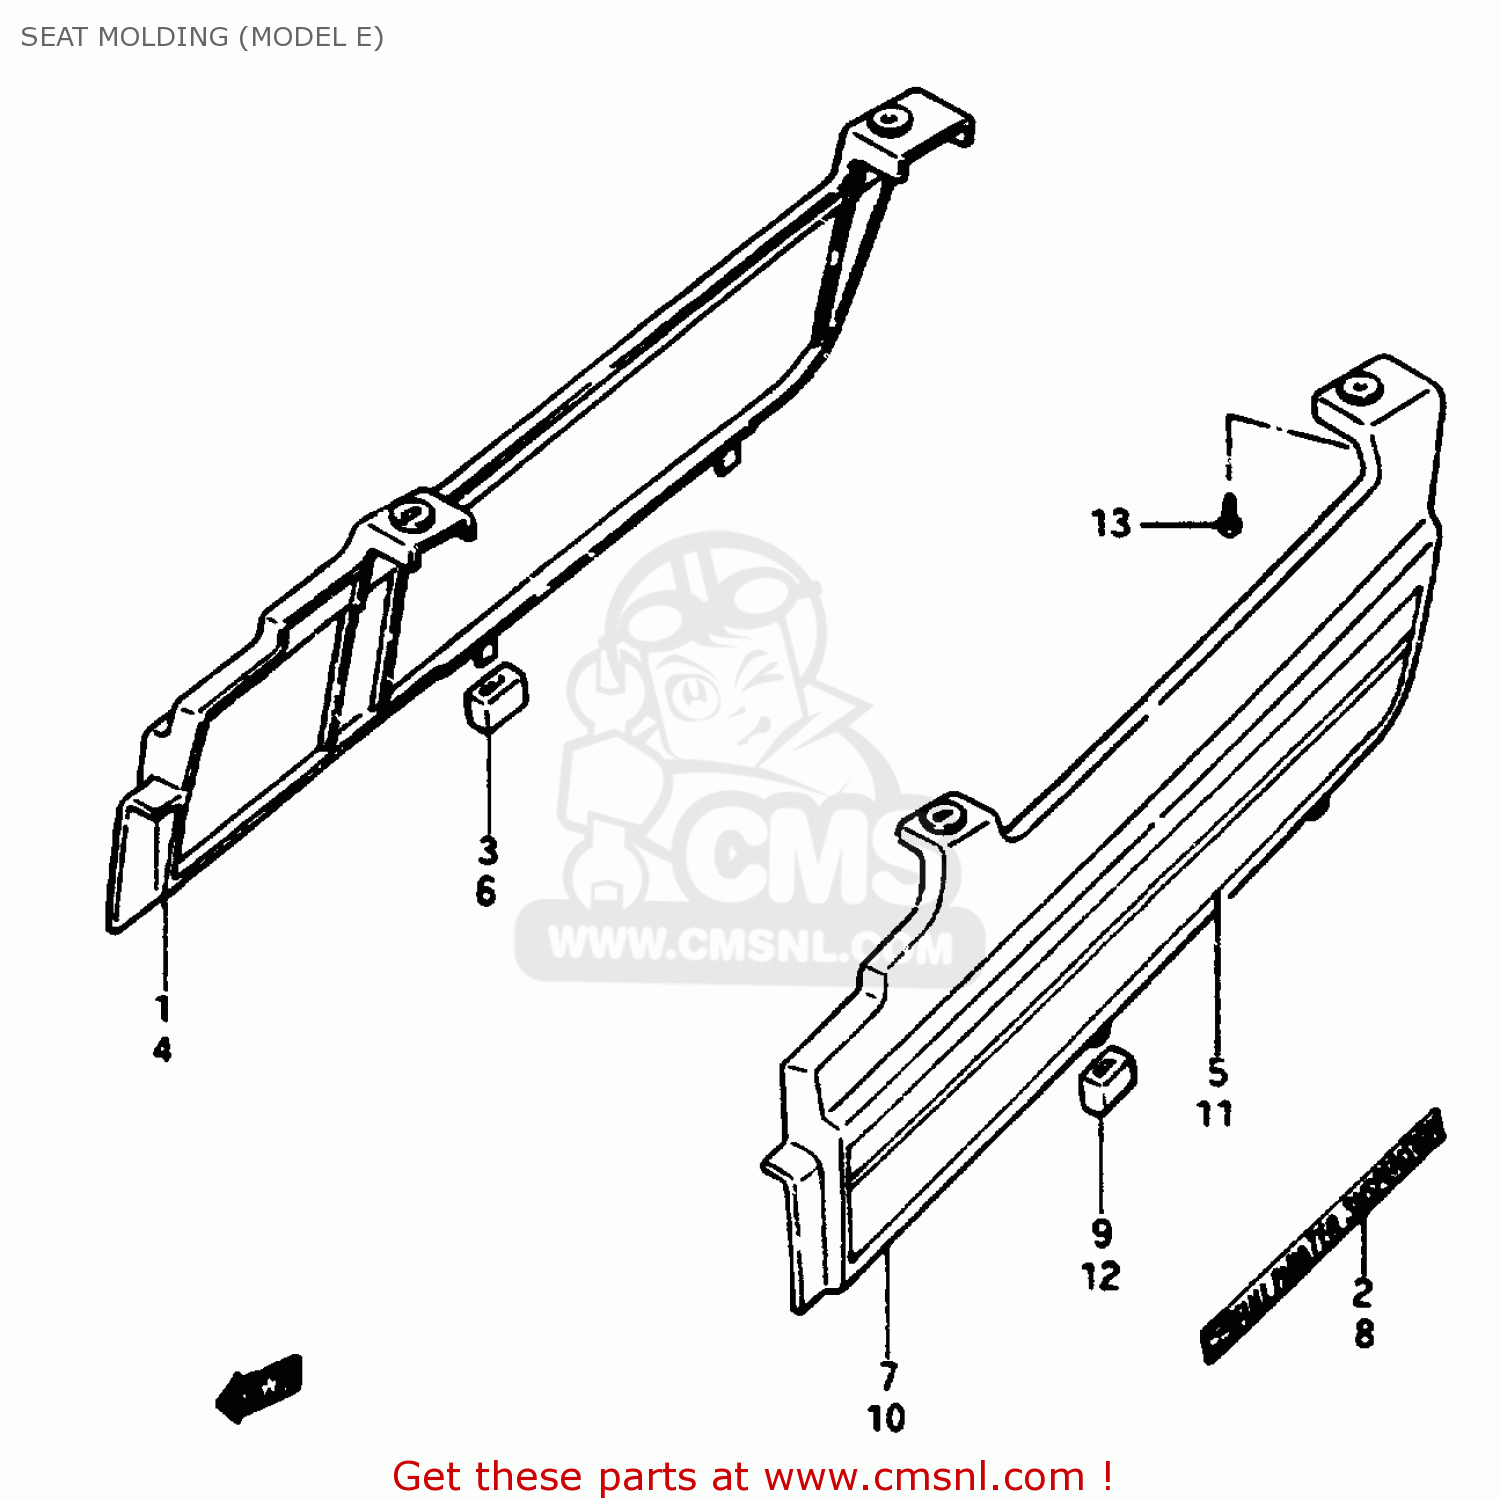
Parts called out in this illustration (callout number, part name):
1	MOLDING, SEAT RH (WHITE)
2	EMBLEM
3	CAP,SEAT MOLDING
4	MOLDING, SEAT RH (BLUE)
5	TAPE SET, RH (WHITE)
6	CAP,SEAT MOLDING
7	MOLDING, SEAT LH (WHITE)
8	EMBLEM
9	CAP,SEAT MOLDING
10	MOLDING, SEAT LH (BLUE)
11	TAPE SET, LH (WHITE)
12	CAP,SEAT MOLDING
13	SCREW
